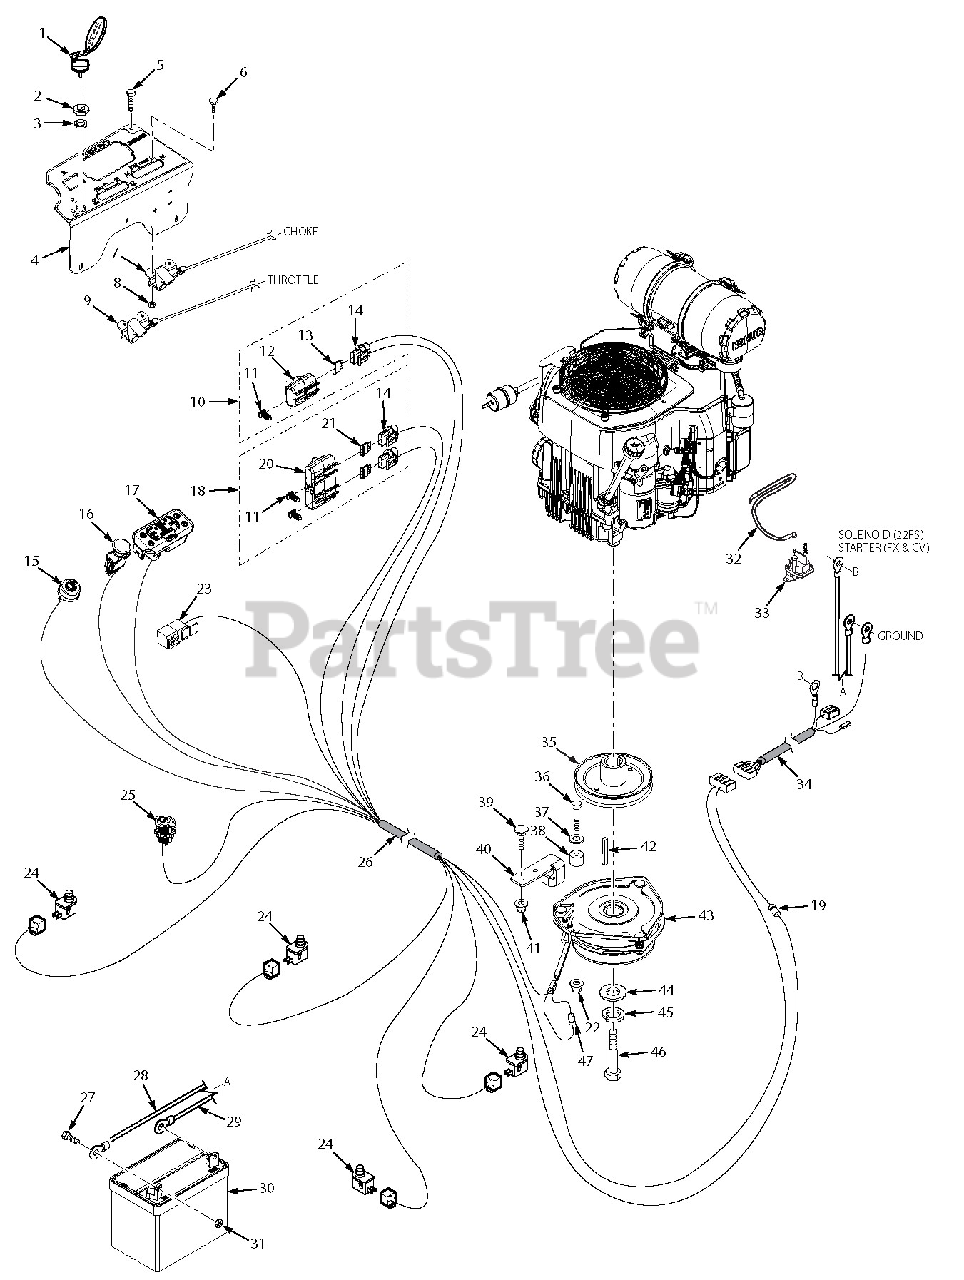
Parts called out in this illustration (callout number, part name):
1	Key, Ignition
2	Nut, Hex 5/8-32
3	Lockwasher, 5/8" Internal
4	Instrument Panel w/Decal
5	Bolt, Hex Head Serrated Flange 1/4-20 x 1/2"
6	Bolt, Carriage #10-24 x 1/2"
7	Choke Control Cable (Kawasaki FS / FX)
7	Choke Control Cable (Kohler CV)
8	Locknut, #10-24
9	Throttle Control Cable (Kawasaki FS / FX, Kohler CV)
10	Single Fuse Assy.
11	Clip, Wire
12	Cover, Sealed Single
13	Fuse, 5 Amp
14	Fuse Holder
15	Switch, Starter
16	Switch, PTO
17	Cluster Gauge
18	Double Fuse Assy.
19	Diode
20	Cover, Sealed Double
21	Fuse, 20 Amp
22	Nut, Elastic Stop 5/16-18
23	Relay
24	Switch
25	Power Plug
26	Wire Harness
27	Bolt, Hex Head 1/4-20 x 1/2"
28	Battery Cable, 25" Red
29	Battery Cable, 27" Black
30	Battery, 350 CCA
31	Nut, 1/4-20 UNC
32	Battery Cable, Red 9" (Kawasaki 22FS)
33	Solenoid, Sealed (Kawasaki 22FS)
34	Wire Harness Adapter, Kawasaki - 22FS
34	Wire Harness Adapter, Kawasaki - 22FX & 23FX
34	Wire Harness Adapter, Kohler - 23CV
35	Pulley, 5.75" Dia. - 1.125 Bore
36	Bolt, Hex Head 5/16-18 x 1-1/2"
37	Flatwasher, 5/16-.375 x .875 x .083
38	Bushing, UHMW
39	Bolt, Carriage 5/16-18 x 3/4"
40	Anti-Rotation Bracket
41	Nut, Flange Elastic Stop 5/16-18
42	Key, 1/4 x 1/4 x 3-1/2"
43	Clutch, GT3.5 - 1.125 Bore
44	Flatwasher, 7/16-.469 x 1.75 x .25
45	Lockwasher, 7/16" Spring
46	Bolt, Hex Head 7/16-20 x 2-1/4" w/Patch
47	Diode, 600V - 6A
